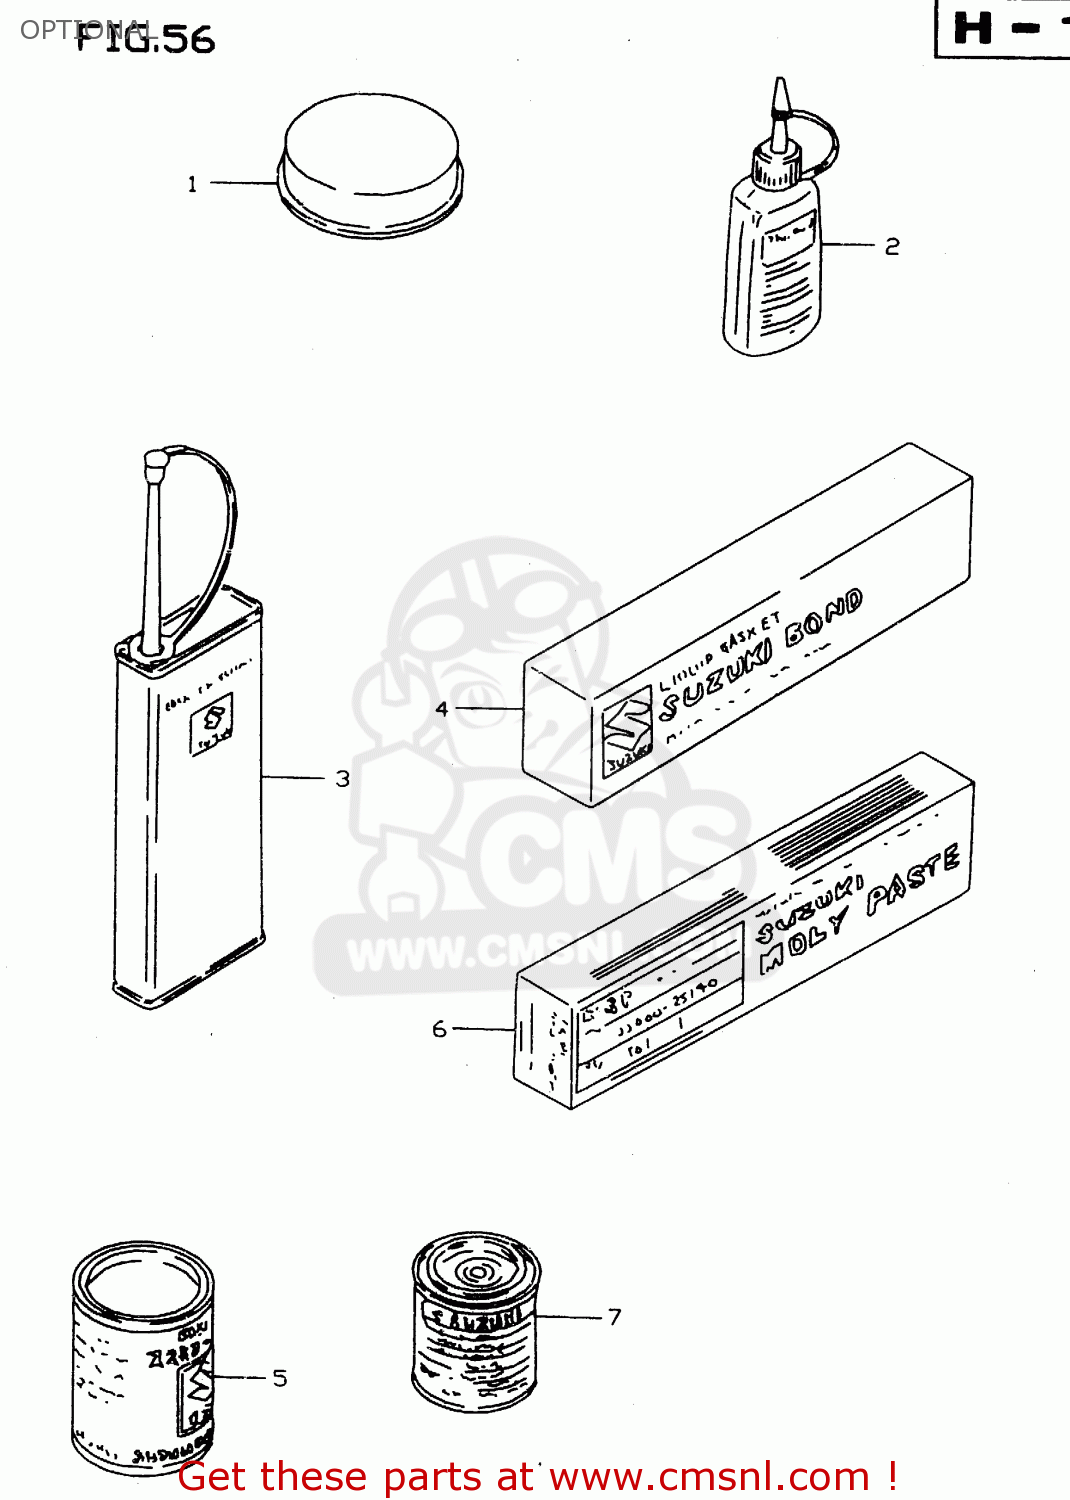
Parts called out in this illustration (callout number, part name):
1	GREASE,PBC FOR BRK PAD 20G
2	THREAD LOCK NO.1342
3	THREAD LOCK NO.1401 CLEAR 200G
4	LIQUID GSKT NO.1215 250G
5	GREASE(C)EP2 LITHIUM 150G
6	SUZUKI MOLY PASTE
7	PAINT,BLACK
